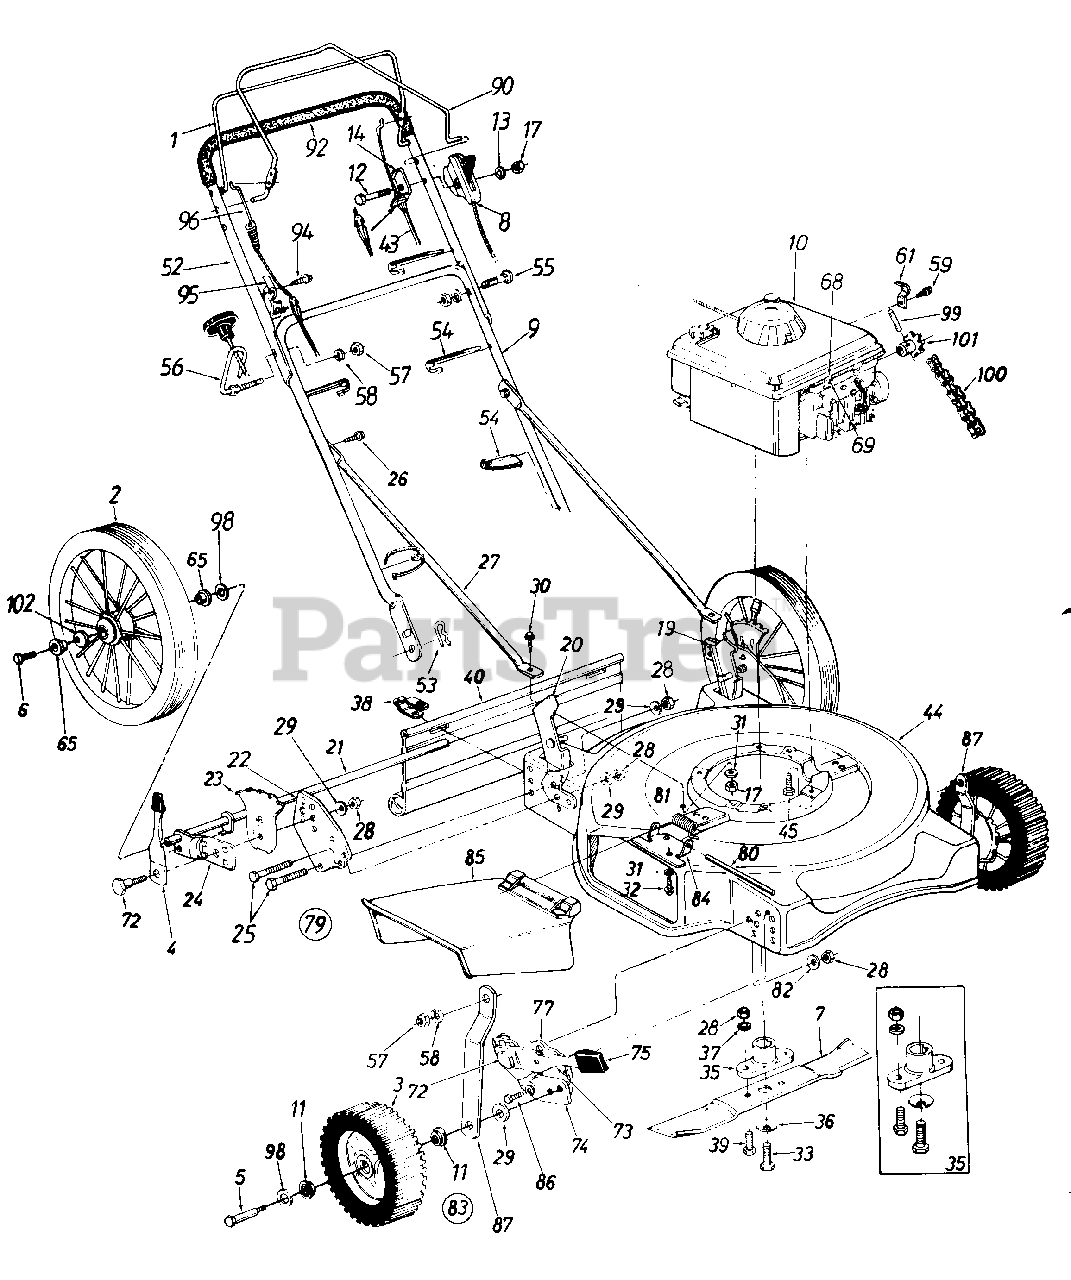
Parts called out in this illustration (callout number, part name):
1	Control Handle Ass'y.
2	Rear Wheel Ass'y.-Comp. 14.0 x 1.75
3	Front Wheel Ass'y.-Comp. 8.0 x 1.75
4	Spring Lever Ass'y. w/Knob
5	Front Axle Bolt
6	Hex Bolt 1/4-20 x .62" Lg.
7	22" Blade
8	Throttle Control Ass'y. Comp.- 51 .62"
9	Lower Handle
10	4 H.P. Engine-See Breakdown
11	Flange Brg. 1/2" I.D.
12	Hex Bolt 1/4-20 x 1.75" Lg.
13	Spr. Wash. .265" I.D.
14	Cable Mtg. Bracket
17	Hex Nut 1/4-20 Thd.
19	Handle Mount Brkt.-L.H.
20	Handle Mount Brkt.-R.H.
21	Rear Axle Ass'y.
22	Mounting Plate
23	Height Adj. Plate
24	Order Height Adj. Ass'y. Comp.
25	Hex Bolt 3/8-16 x .75" Lg.
26	Hex Wash. AB-Tap Scr. 5/1 6 x .75" Lg.
27	Strut Bar 22.95" Lg.
28	Hex Nut 3/8-16 Thd.
29	Bell-Wash. .400" I.D. x .88"
30	Hex Bolt 1/4-20 x .62" Lg.
31	Bell-Wash. .265" I.D. x .75" O.D.
32	Hex Wash. Hd. Tap Scr. 1/4-20 x .5" Lg .
33	Hex Bolt 3/8-24 x 1.5" Lg. (Grade 5)
35	Blade Adapter Kit
36	Bell-Wash..39" I.D.
37	L-Wash. 3/8" I.D.
38	Hinge Clip
39	Hex Bolt 3/8-16 x 1" Lg.
40	Rear Flap Ass'y.
43	Control Cable-39"
44	22" Deck Ass'y.
45	Hex Wash. Hd. TT-Tap Scr. 3/8-16 x 1.00" Lg.
52	Upper Handle
53	Intern. Cot. Pin 5/16" Dia.
54	Cable Tie
55	Curved Carriage Bolt 5/16-18 x 1.38" Lg.
56	Rope Guide Bolt
57	Hex Nut 5/16-18 Thd.
58	L-Wash. 5/16" I.D.
59	Hex B-Tap Scr. #10 x .38" Lg.
61	Casing Clamp
65	Flange Bearing
68	Casing Clamp
69	Hex B-Tap Scr. #10 x .62" Lg.
72	Shoulder Bolt .50" Dia.
73	Spring Lever
74	Pivot Bar-R.H.
75	Spring Lever Knob
77	Index Plate
79	Rear Height Adj. Ass'y. Comp.-R.H.
80	Hinge Pin
81	Torsion Spring
82	Bell-Wash. .39" I.D. x 1.38"
83	Front Height Adj. Ass'y. Comp.-R.H.
84	Adapter Plate
85	Chute Deflector Ass'y. Comp.
86	Hex Hd. AB-Tap Scr. 1/4 x .62" Lg.
87	Link
90	S.P. Bail Ass'y.
92	Foam Grip
94	Hex Wash. AB-Tap Scr. 5/16 x.75" Lg.
95	Cable Mounting Brkt.
96	Drive Cable
98	Fl-Wash. .531" I.D. x .93"
99	Spring Pin 3/16" Dia.
100	#48 Chain 1/2" Pitch 50 Links
101	10 Tooth Sprocket Ass'y.
102	Bell-Wash. 1/4" I.D.
